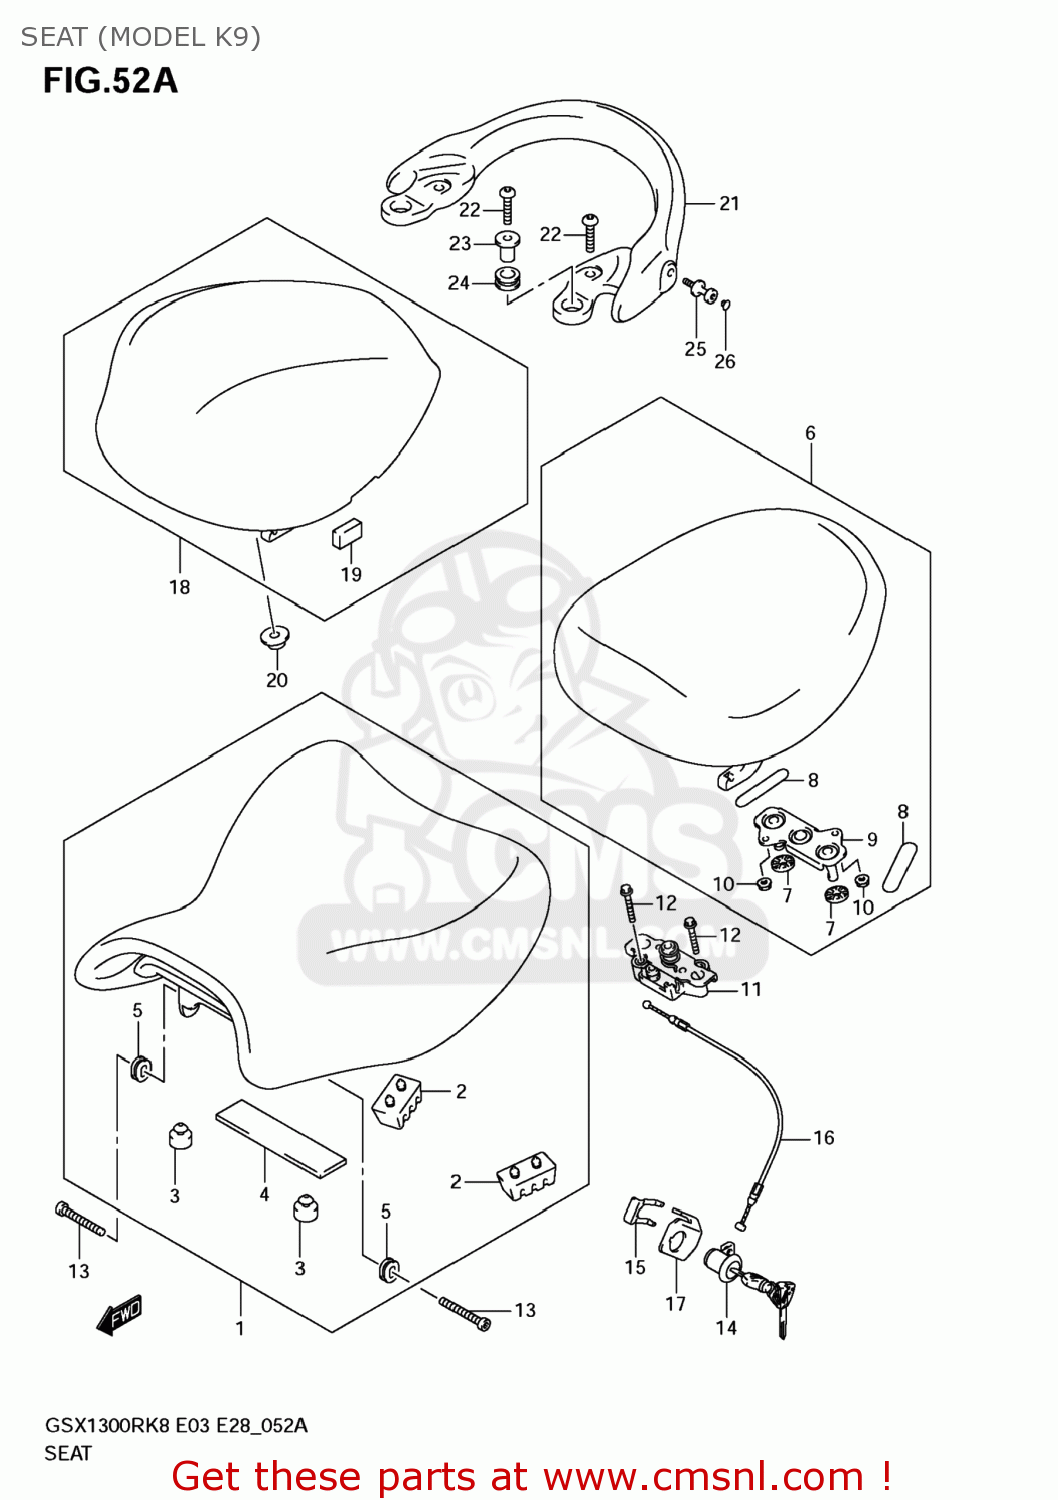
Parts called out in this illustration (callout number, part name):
1	SEAT ASSY
2	CUSHION,SUPPORT(50X25X32)
3	CUSHION
4	CUSHION
5	CUSHION
6	SEAT ASSY,PILL
7	CUSHION
8	CUSHION
9	STRIKER,SEAT LOCK
10	NUT
11	BRACKET,STRIKER SUPPORT
12	BOLT
13	BOLT,SEAT FR
14	LOCK SET,SEAT
15	PLATE,SEAT LOCK ASSY
16	CABLE,SEAT LOC
17	GUIDE,SEAT LOCK CABLE
18	BOX COMP,SEAT
19	CUSHION
20	WASHER,FRAME COVER
21	HANDLE,PILLION RIDER
22	BOLT(8X33)
23	WASHER,PILLION
24	CUSHION,PILLION RIDER HANDLE
25	HOOK,PILLION RIDER HANDLE
26	CAP(OD:10)
